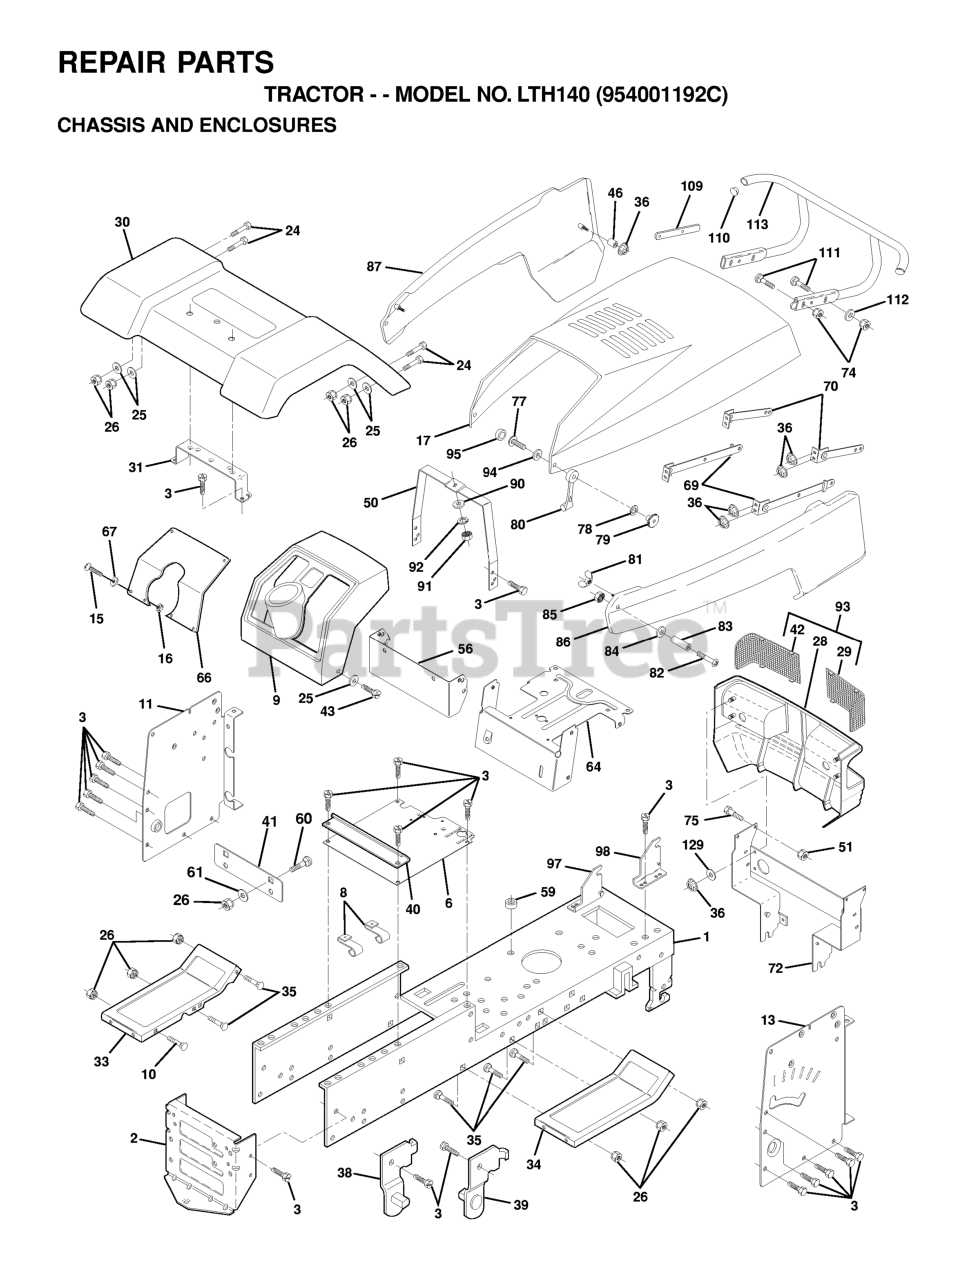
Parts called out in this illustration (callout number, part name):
1	CHASSIS WELD 11GA.95
2	STRETCH DRAWBAR
3	SCREW
6	SADDLE LT FENDER
8	CLIP,INSULATOR
10	BOLT D
11	PANEL DASH LT
13	PANEL DASH RH
15	Screw, Machine, Truss Head 5/16-18 UNC x 3/4
16	NUT
17	HOOD.HUSQVARNA.ORANGE
25	WASHER
26	NUT
28	GRILL
29	LENS RH
30	FENDER
31	BRACKET.SUPPORT.FENDER
33	FOOT REST LH
34	FOOTREST RH
36	PAL NUT LT
38	BRACKET LH PIVOT
39	BRACKET RH PIVOT
41	PLATE
42	LENS LH
43	SCREW GTV
50	DASH SUPT YP
51	LOCKNUT.NYLOC.1/4-20
56	DASH EXT PNT
59	SNAP BUSHING T
60	Bolt - Rd. Hd. Sq. Neckiage 3/8 16 x 3/4
61	Washer 1 17/32 X 7/8 X 16 Ga
64	DASH LOWER YT
66	DASH PLATE
67	WASHER
72	SUPT, ASS'Y GRILL
75	BOLT T
77	SCREW
78	LOCKWASHER #10
79	WELDNUT
80	LATCH.HOOD.
81	NUT.WING.LCK.NYL.NOTCH.1/4-20
82	RP SCREW
85	NUT **
86	PANEL SIDE RH
87	PANEL SIDE LH
91	NUT
92	LOCKWASHER
93	GRILL
95	SNAP CAP LT
97	SUPPORT RH YTH
98	SUPPORT LH YTH
109	BRACKET BUMPER
110	PLUG PLASTIC
111	BOLT.3/8-14X1.25
112	WASHER
113	BUMPER ASSY
